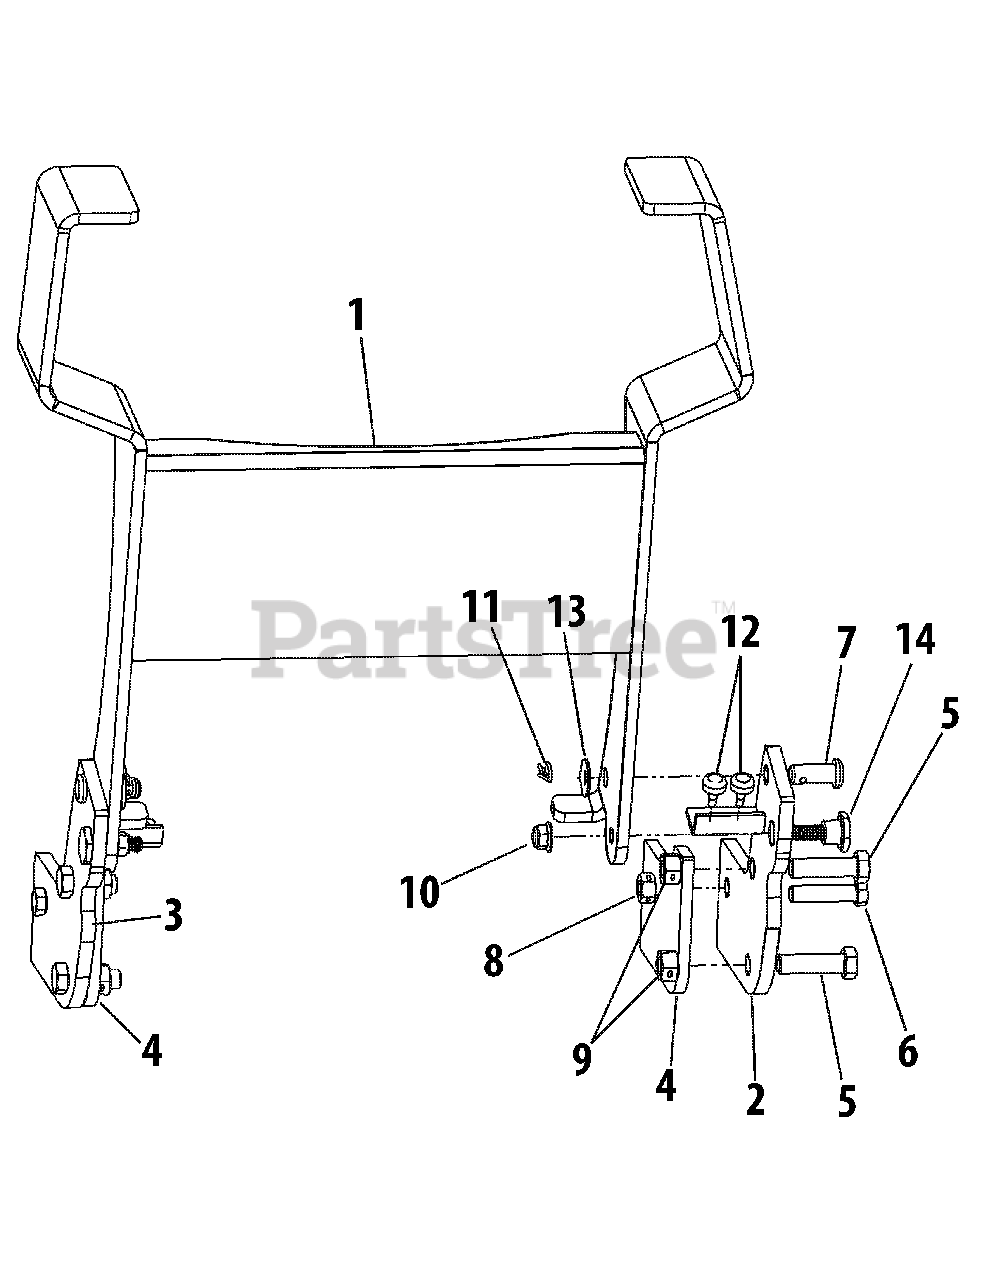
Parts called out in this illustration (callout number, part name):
1	Grill Guard Frame
2	Bracket, Grille Guard Mounting LH
3	Bracket, Grille Guard Mounting RH
4	Spacer, Grille Guard
5	Hex Screw, 1/2-13 x 1.75 Gr5
6	Hex Screw Lock, 7/16-14 x 1.75 Gr5
7	Pin, Clevis, .5 x 1.18
8	Nut, Hex Centerlock, 7/16-14 GrA
9	Nut, Hex Centerlock,, 1/2-13 GrA
10	Nut, Hex Insert Lock, 3/8-16 GrF
11	Pin, Internal Cotter
12	Bumper, Rubber
13	Washer, Flat, .51 x 1.0 x .06
14	Screw, Shoulder, .625 x .442:3/8-16
